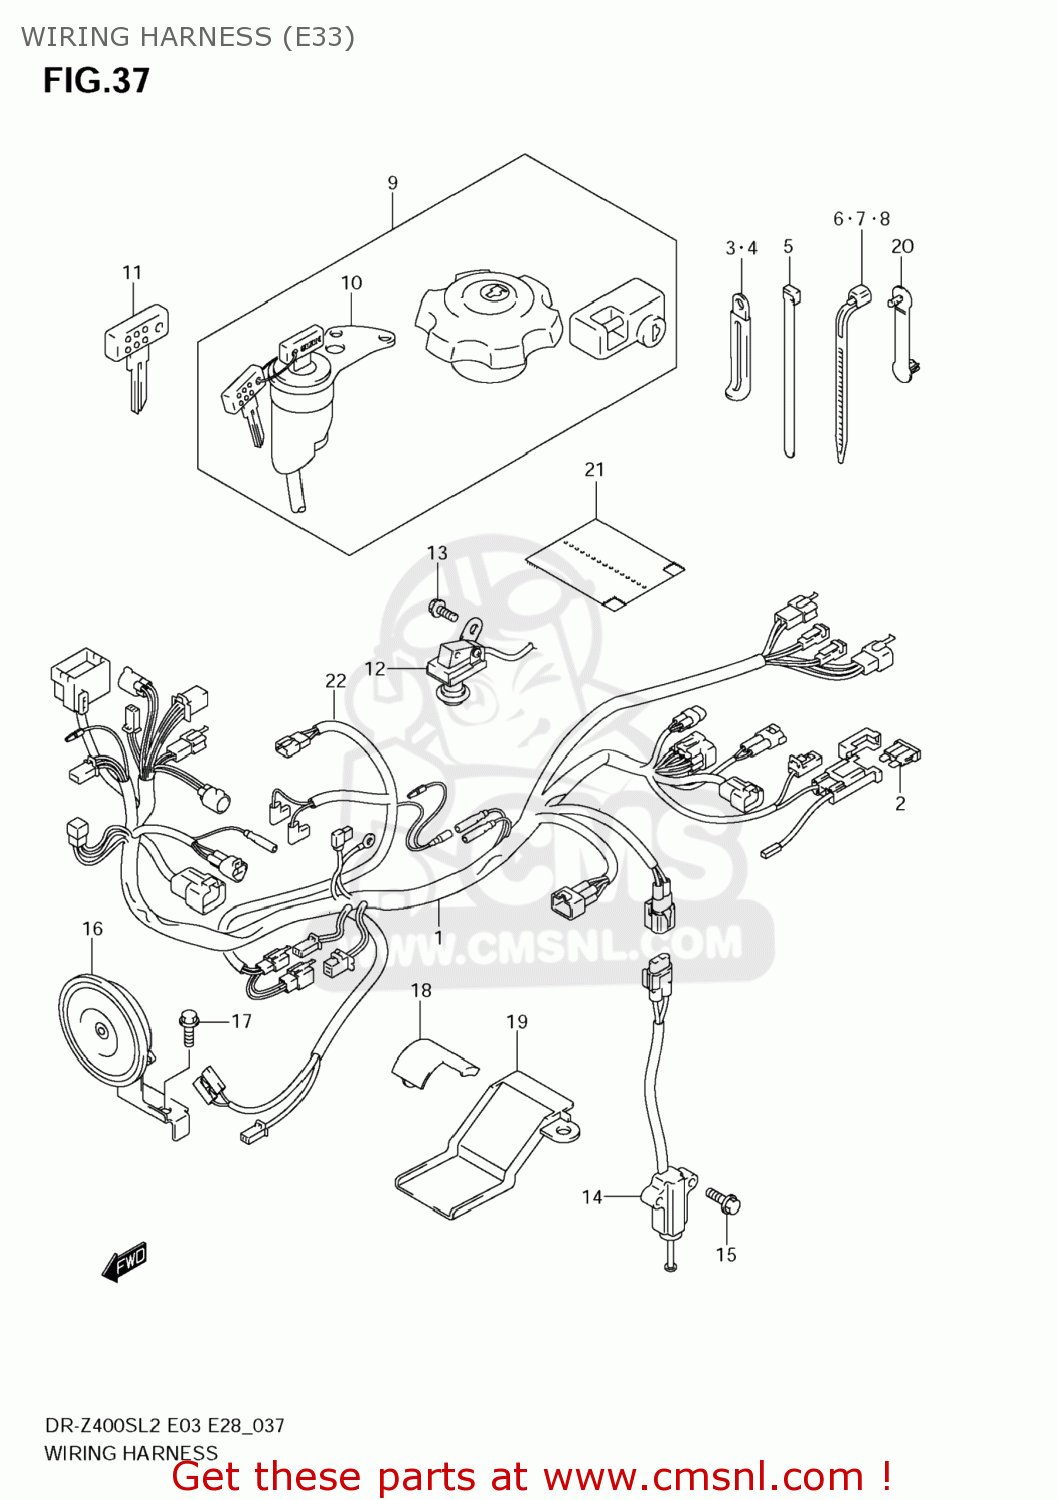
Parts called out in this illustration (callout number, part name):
1	HARNESS,WIRING
2	FUSE(20A)
3	CLAMP(L:45)
4	CLAMP(L:80)
5	CLAMP(L:145)
6	CLAMP(L:125)
7	CLAMP(L:165)
8	CLAMP(L:235)
9	LOCK SET
10	SWITCH ASSY,IGNITION
11	KEY,BLANK(TYPE:C)
12	SWITCH ASSY
13	SCREW
14	SWITCH ASSY,SIDE STAND
15	BOLT
16	HORN ASSY
17	BOLT
18	PROTECTOR,WIRING HARNESS
19	PROTECTOR,WIRING HARNESS
20	CLAMP(L:63)
21	COVER,WIRING HARNESS
22	WIRE,CARB HEATER
